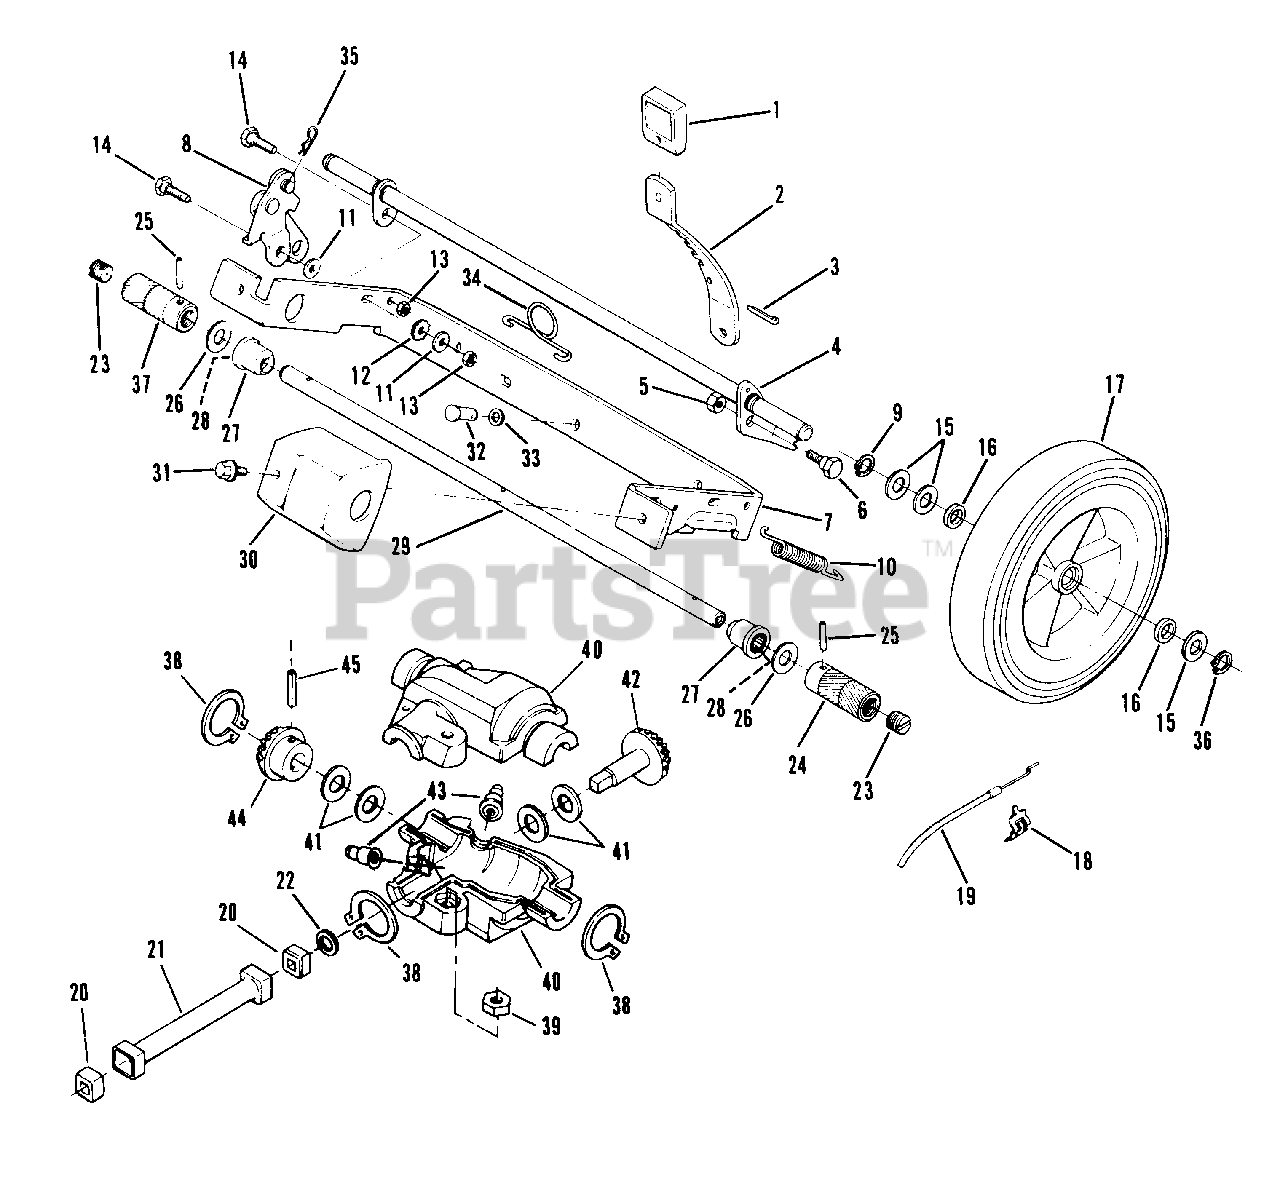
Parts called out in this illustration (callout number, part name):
1	Knob-Rear Ht. Adj. Lever
2	Lever-Rear Height Adjust
3	Cotter Pin
4	Axle Assembly
5	Locknut
6	Bolt-Shoulder
7	Bracket-21" Axle
8	Clutch Assembly
9	Retaining Ring
10	Spring
11	Washer
12	Lockwasher
13	Stop Nut
14	Bolt-Shoulder
15	Washer
16	Washer-Felt
17	Wheel-Rear
18	Clip
19	Cable-Starter Interlock
20	Bushing
21	Tube-Drive
22	"O" Ring-Spacer
23	Plug
24	Drive Roller-L.H.
25	Pin-Spiral
26	Washer
27	Sleeve & Bearing Assembly
28	Needle Bearing
29	Shaft
30	Guard-Roller
31	Screw
32	Pin-Rear Height Adjust Lever
33	Spring Washer
34	Spring-Height Adjust
35	Lock Pin
36	Retaining Ring
37	Drive Roller-R.H.
38	Ring-Retaining
39	Locknut
40	Gear Box Assembly
41	Washer
42	Gear-Drive
43	Zerk Fitting
44	Gear-Driven
45	Spring Pin
